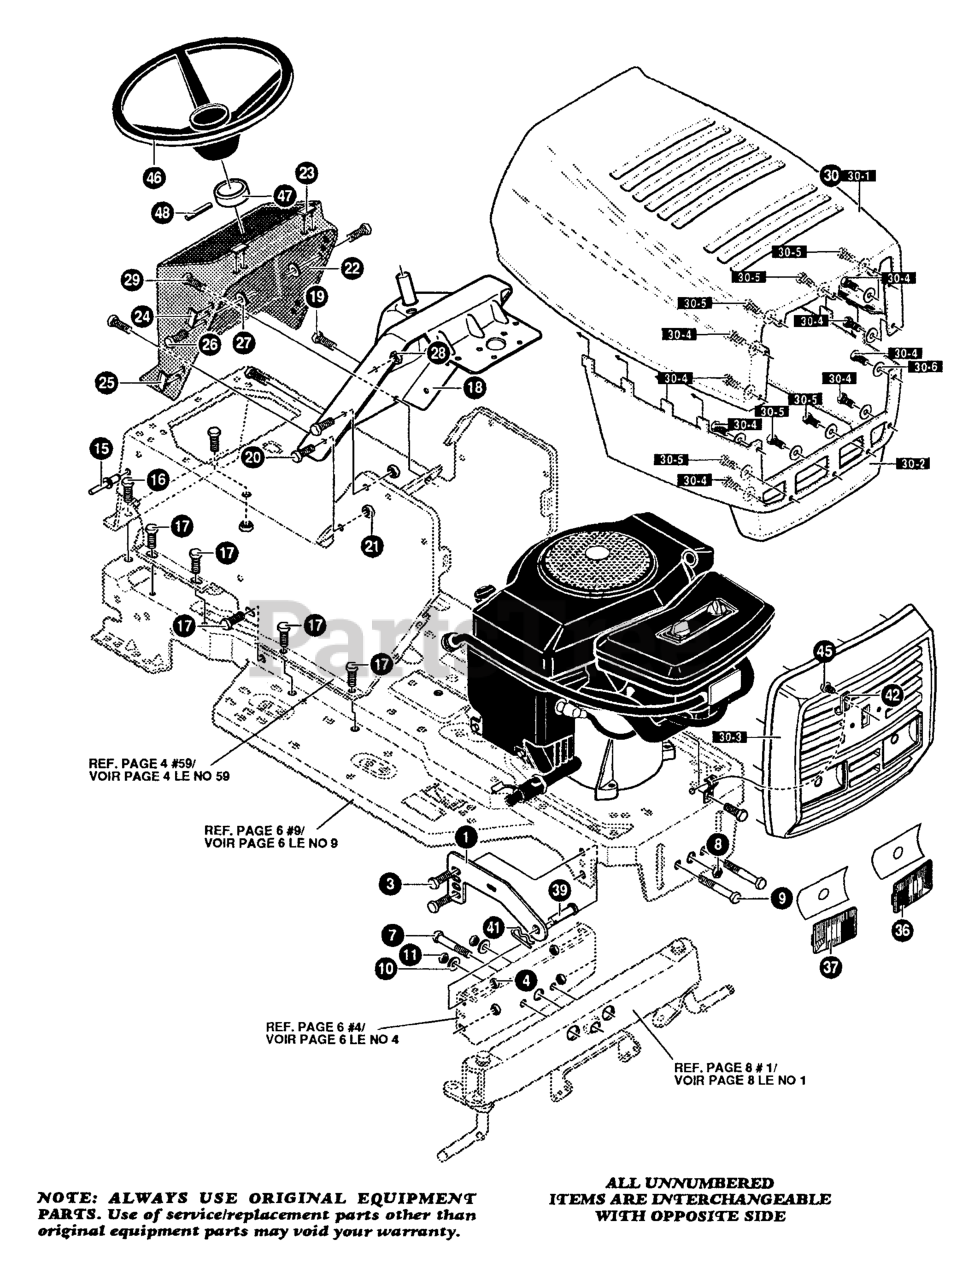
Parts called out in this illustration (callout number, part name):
1	BRACKET, HOOD
3	SCREW
10	WASHER
11	NUT
23	BUMPER, HOOD
24	BUMPER, HOOD
25	BUMPER, HOOD
30	HOOD ASSY
30-2	SKIRT, HOOD
30-3	GRILLE
30-6	WASHER
36	LENS, LH
37	LENS, RH
39	PIN, CLEVIS
41	PIN, HAIR
42	LANYARD, HOOD
45	SCREW
46	STEERING WHEEL
47	SPACER, STEER SHAFT
48	PIN, SPRING
